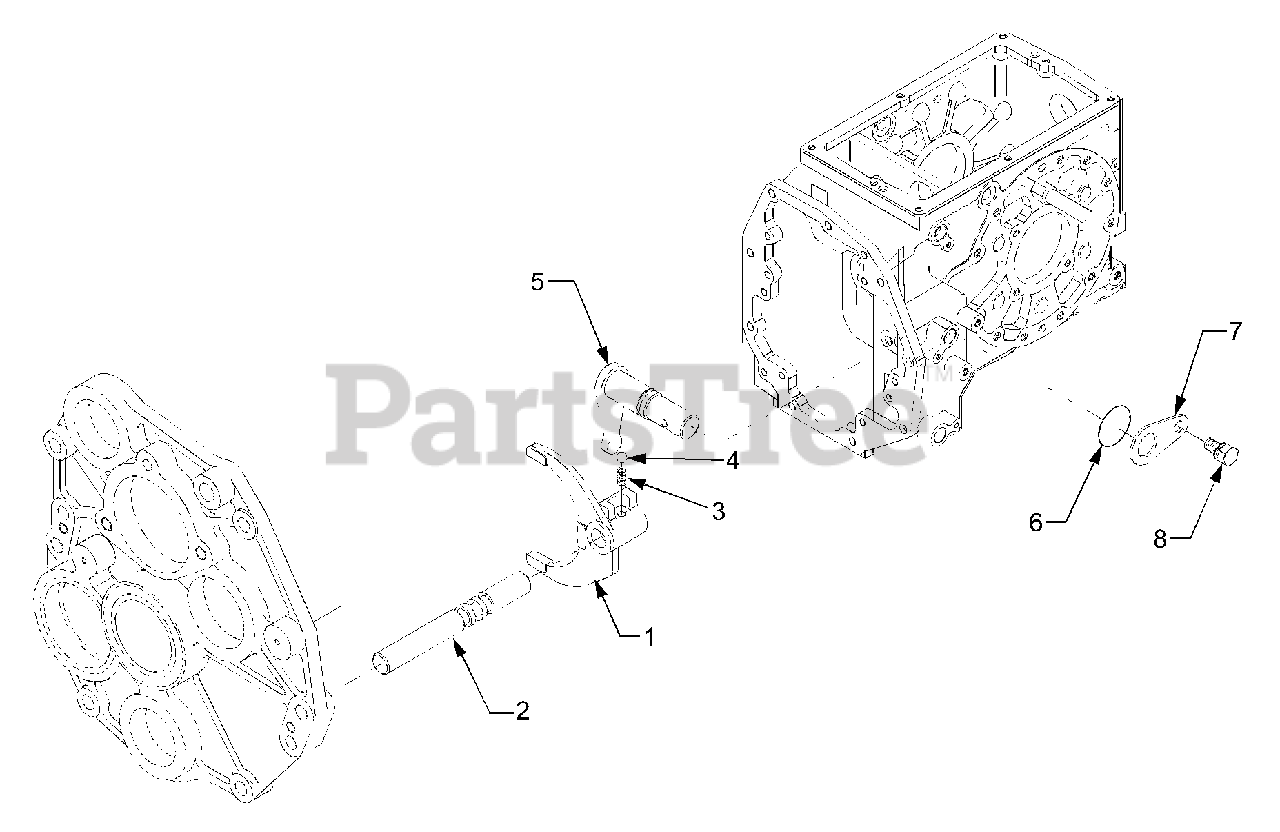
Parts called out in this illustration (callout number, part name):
1	Fork, Shift (Range)
2	Rod, Range Shift
3	Spring, Stopper
5	Arm, Range Shift
